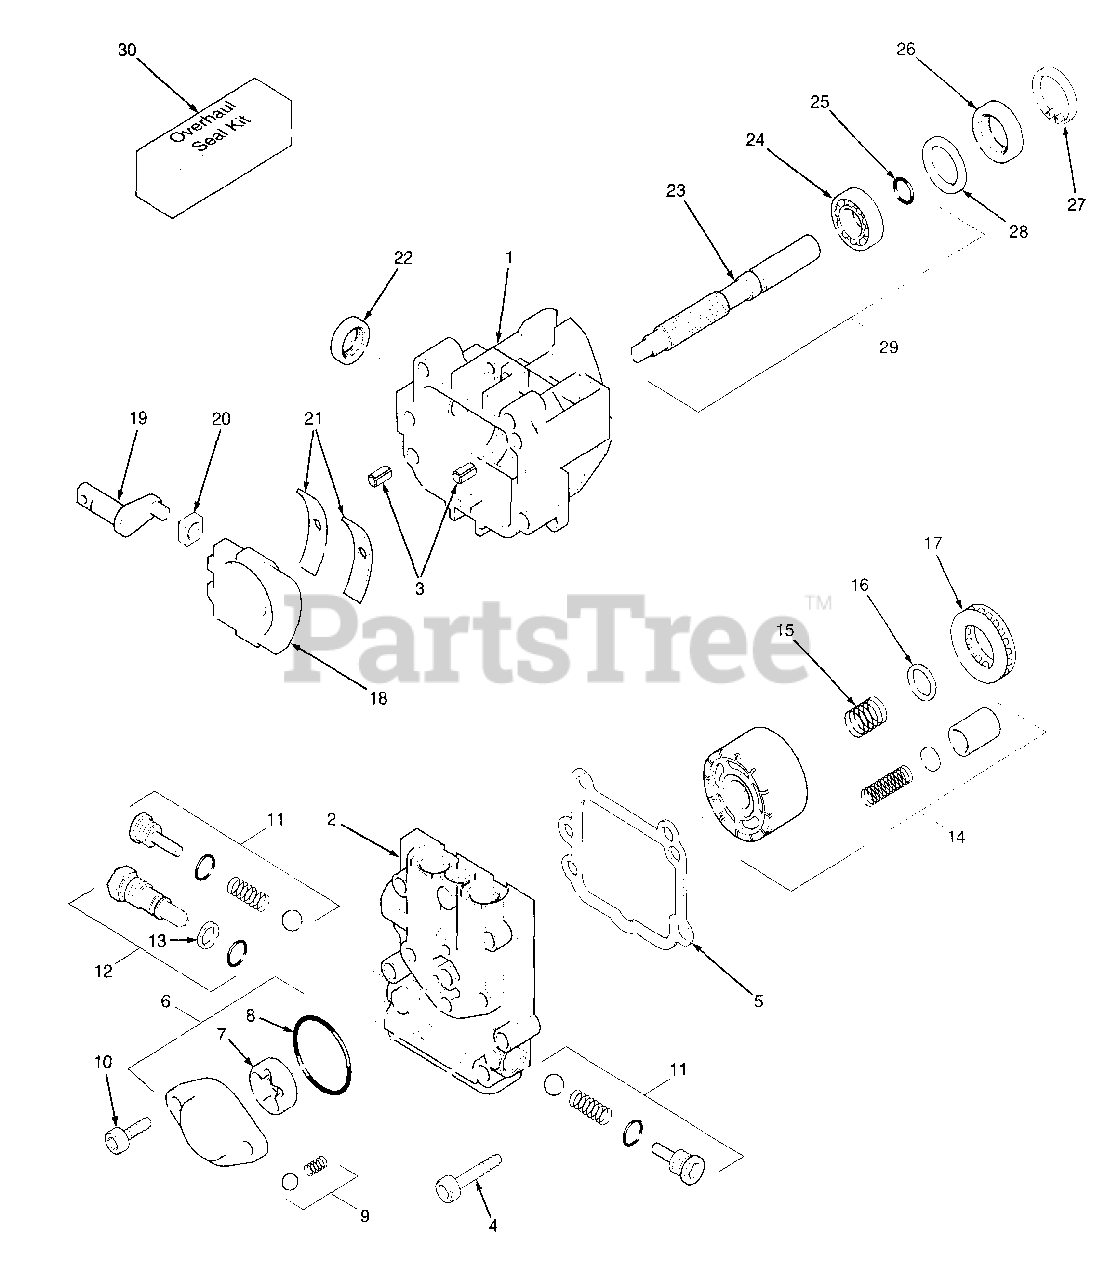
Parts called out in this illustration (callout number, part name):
1	Housing Kit
2	End Cap
3	Straight Headless Pin
4	Socket Head Screw
5	End Cap Gasket
6	Charge Pump Kit
7	Gerotor Assembly
9	Charge Relief Valve Kit
10	Socket Head Screw
11	Check Valve Kit
12	Bypass Valve Kit
13	Backup Ring
14	Cylinder Block Kit
15	Block Spring
16	Black Thrust Washer
17	Roller Thrust Bearing
18	Swash Plate
19	Trunnion Arm
20	Guide Slot
21	Cradle Bearing
23	Pump Shaft
24	Ball Bearing
25	Retaining Ring
27	Retaining Ring
28	Spacer
29	Shaft Kit
30	Overhaul Seal Kit
